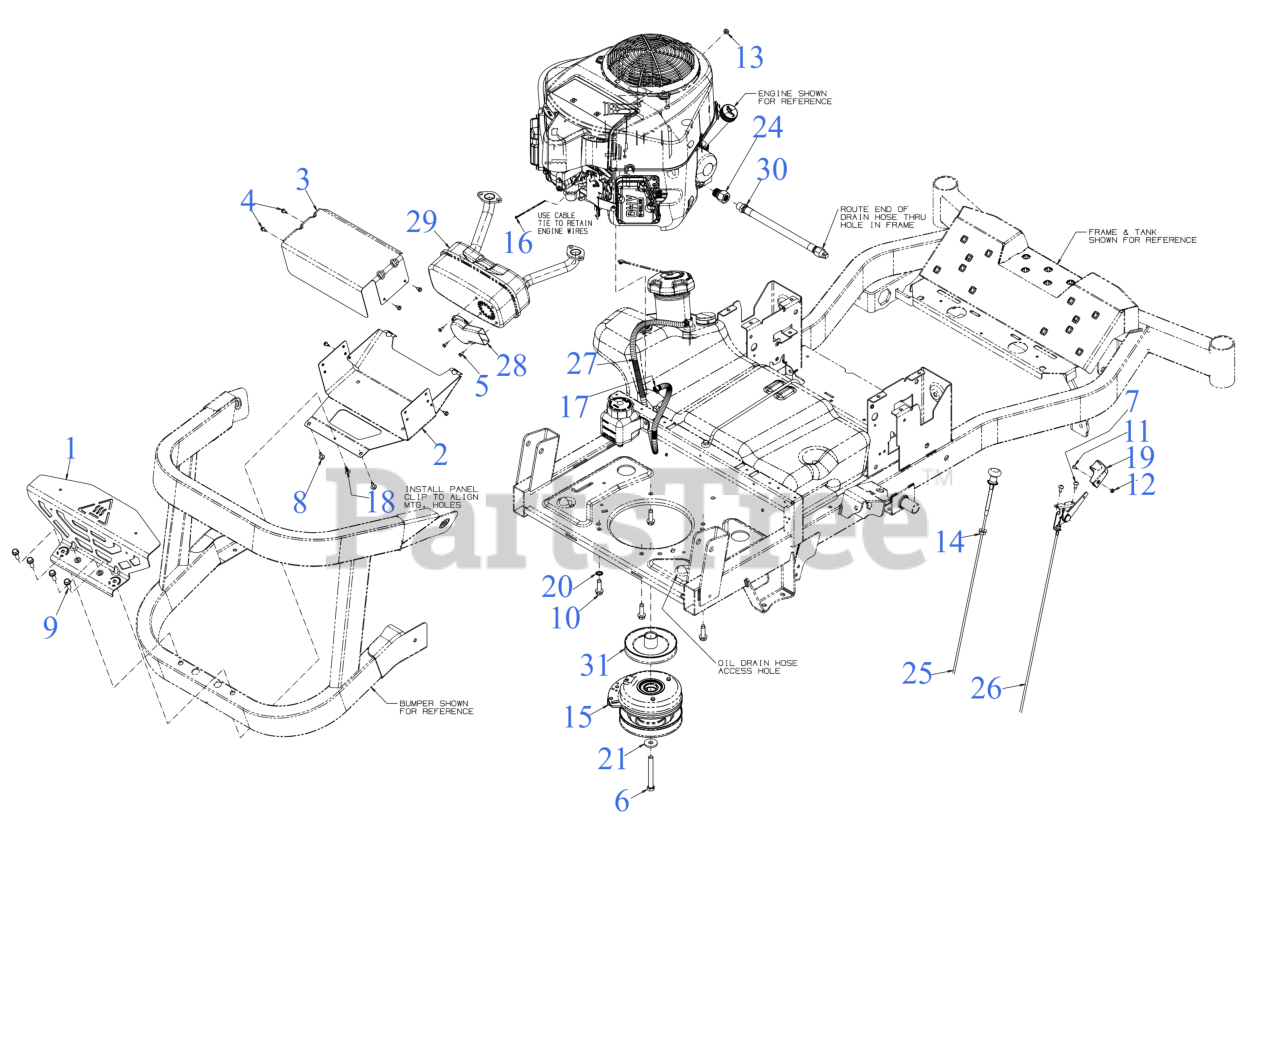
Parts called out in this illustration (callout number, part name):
1	MUFFLER COVER (REAR) (BLACK)
1	NUT RIVET 5/16-18
2	MUFFLER SHIELD (LOWER)
3	MUFFLER SHIELD (TOP)
4	HEX SCREW AB-TAP #10 x .50
5	HEX SCREW WASHER HD #8-18 x 0.500
6	SCREW 7/16-20 x 3.5 GR5
7	SCREW 1/4-20 x .5
8	SCREW M6-1 x .625
9	SCREW 5/16-18 x .875 GR5
10	SCREW 3/8-16 X1.250
11	SCREW #8-32X.38 LG
12	HEX NUT 8-32
13	HEX NUT 1/4-20
14	HEX FLANGE NUT
15	ELECTRIC PTO CLUTCH
16	CABLE TIE
17	HOSE CLAMP 1/20
18	RATCHET CLIP (.188 x .85)
19	THROTTLE CONTROL KNOB
20	LOCK WASHER 3/8
21	FLAT WASHER .445 x 1.248 x .170
24	OIL DRAIN FITTING (M20x2.5)
25	CHOKE CABLE 40.5 LG
26	THROTTLE CABLE 38.5"
27	FUEL HOSE LOW PERMEATION 28"
28	EXHAUST DELECTOR (LONG)
29	EXHAUST MUFFLER
30	OIL DRAIN HOSE (11.26" 3/8 NPT)
31	TRANSMISSION DRIVE PULLEY
